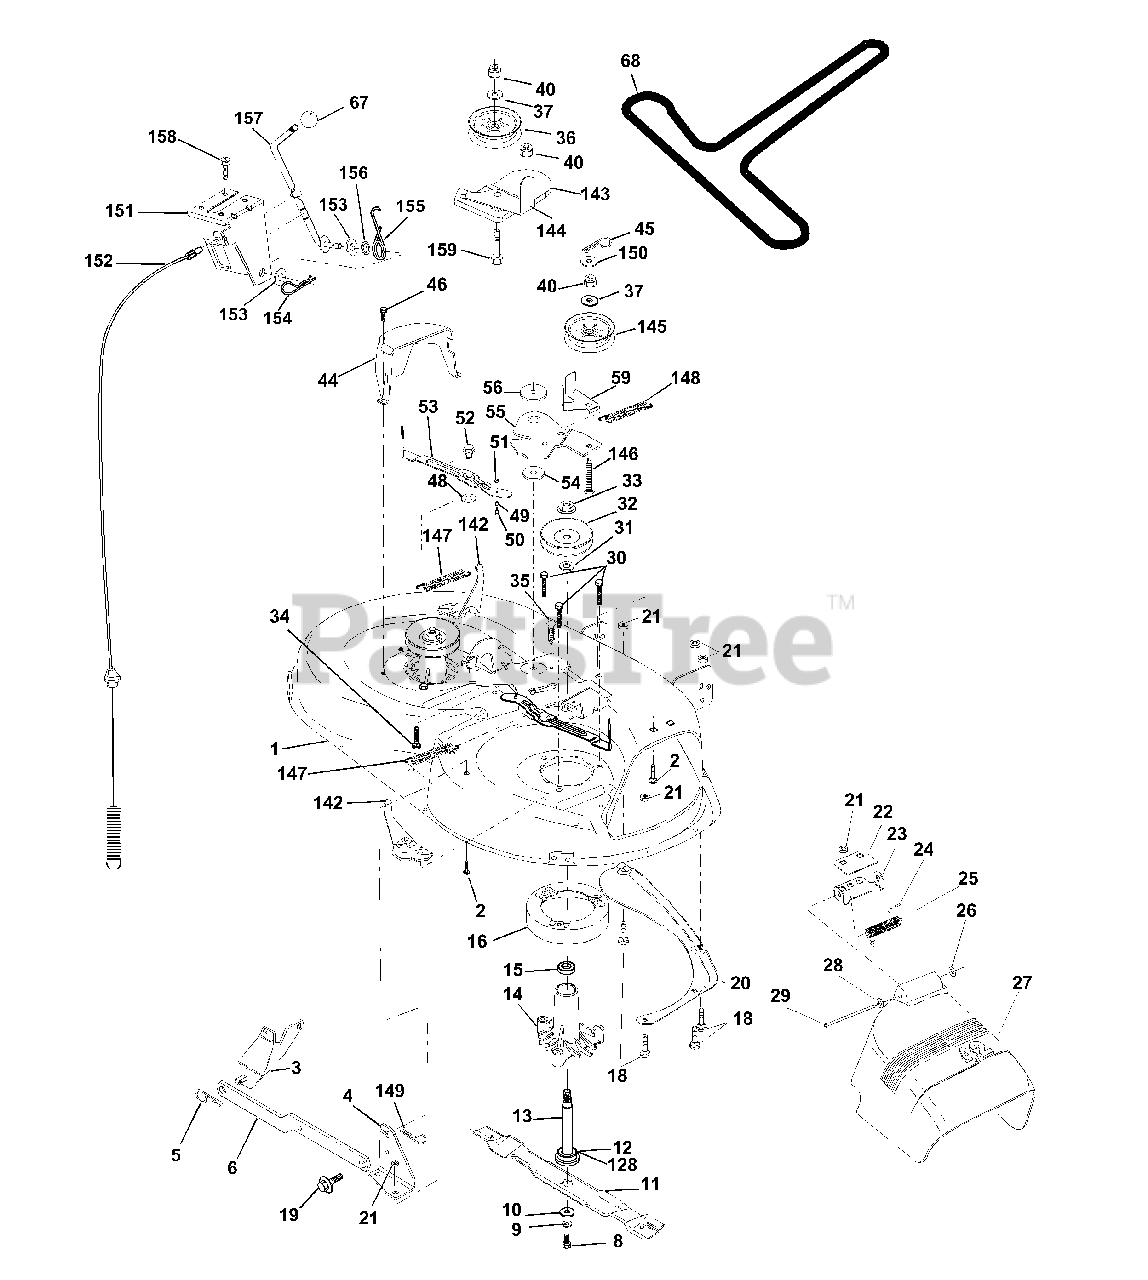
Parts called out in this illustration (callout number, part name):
1	Mower Deck Assembly, 42"
2	Bolt
3	Bracket Asm Fr. Sway Bar 3/42
4	Bracket Asm Deck 42" Sway Bar
5	Retainer Spring
6	Arm, Suspension, Rear
8	Bolt 3/8-24 x 25 Grade 8 patched
9	Washer, Lock
10	Washer,Hardened
11	Blade
12	Bearing, Ball #6204
13	Shaft Assembly, Mandrel, Vented
14	Housing, Mandrel, Vented
15	Bearing, Ball, Mandrel
16	Stripper, Vented Mower Deck
18	Bolt, Carriage 5/16-18 x 5/8
19	Bolt, Shoulder
20	Baffle, Vortex
21	Nut
22	Stiffener Bracket
23	Bracket, Deflector Mower 42"
24	Cap, Sleeve 80 x 112 Blk Mower
25	Spring, Torsion, Deflector 2 52
26	Nut, Push Phos & Oil
27	Shield, Deflector 42" Blk
28	Washer 11/32 x 5/8 x 16 Gauge
29	Rod, Hinge 42" 6 75 W/G
30	Screw Thdrol Washer Head
31	Washer, Spacer Mower Vented
32	Pulley, Mandrel
33	Nut, Toplock 9/16
34	Bolt
35	Fastener, Christmas Tree
36	Pulley, Idler, Flat
37	Washer 13/32 x 13/16 x 16 Gauge
40	Nut
44	Guard, Mandrel, LH
45	Retainer
46	Screw, Thdrol 1/4-20 x 5/8 T
48	Washer, Hardened
49	Roller Assembly, Cam Follower
50	Bolt, Shoulder #10-24 Grade 5
51	Locknut
52	Bolt, Shoulder 5/16-18 UNC
53	Arm Assembly, Pad, Brake
54	Washer,Hardened
55	Arm, Idler
56	Spacer, Retainer
59	Guard TUV Idler
67	Knob
68	V-Belt, 42" Mower
128	Washer, Felt
142	Arm Spring Brake Mower
143	Bracket Arm Idler 42"
144	Keeper Belt 42" Clutch Cable
145	Pulley Idler Flat
146	Bolt Carriage Idler
147	Spring Extension
148	Spring Return Idler
149	Retainer Spring Yellow
150	Washer 9/32 x 3/4 x 16 Ga.
151	Bracket Clutch Cable
152	Clutch Cable 42"
153	Washer Flat 3/8" Type B
154	Spring Retainer
155	Spring Retention LVR CLTCH CAB
156	Spacer Clutch Cable
157	Rod Clutch Cable 3/8"
158	Screw Hex Thd Cut 1/4-20 x 5/8
159	Bolt Rdhd Sqn 3/8-16 UNC x 1-3/4
